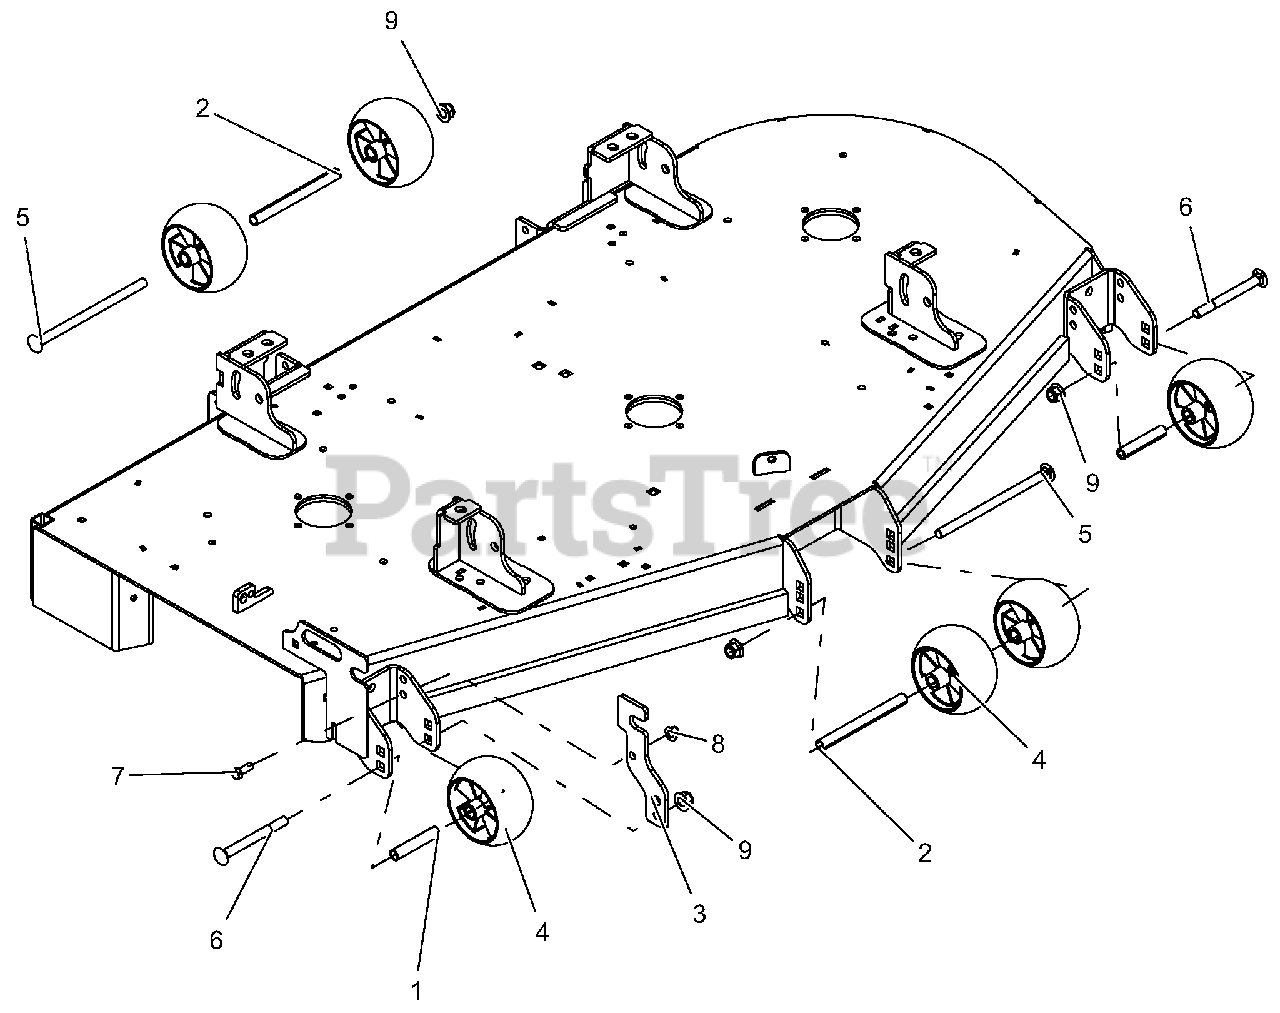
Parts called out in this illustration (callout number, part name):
1	SPACER, .510X.625X3.35
2	SPACER, .510X.625X6.70
3	CHUTE STORAGE BRACKET-RED
4	ANTI-SCALP WHEEL - 5X3 CTR
5	@BLT-RDHDSQNK .50-13X8.50 Y
6	BLT-RDHDSQNK .50-13X5.00 G5
7	BLT-HEX .38-16X1.00 GR5 YWZC
8	NUT-LK-NYL-FLG .38-16 YWZC
9	NUT-LK-NYL-FLG .50-13 YWZC
